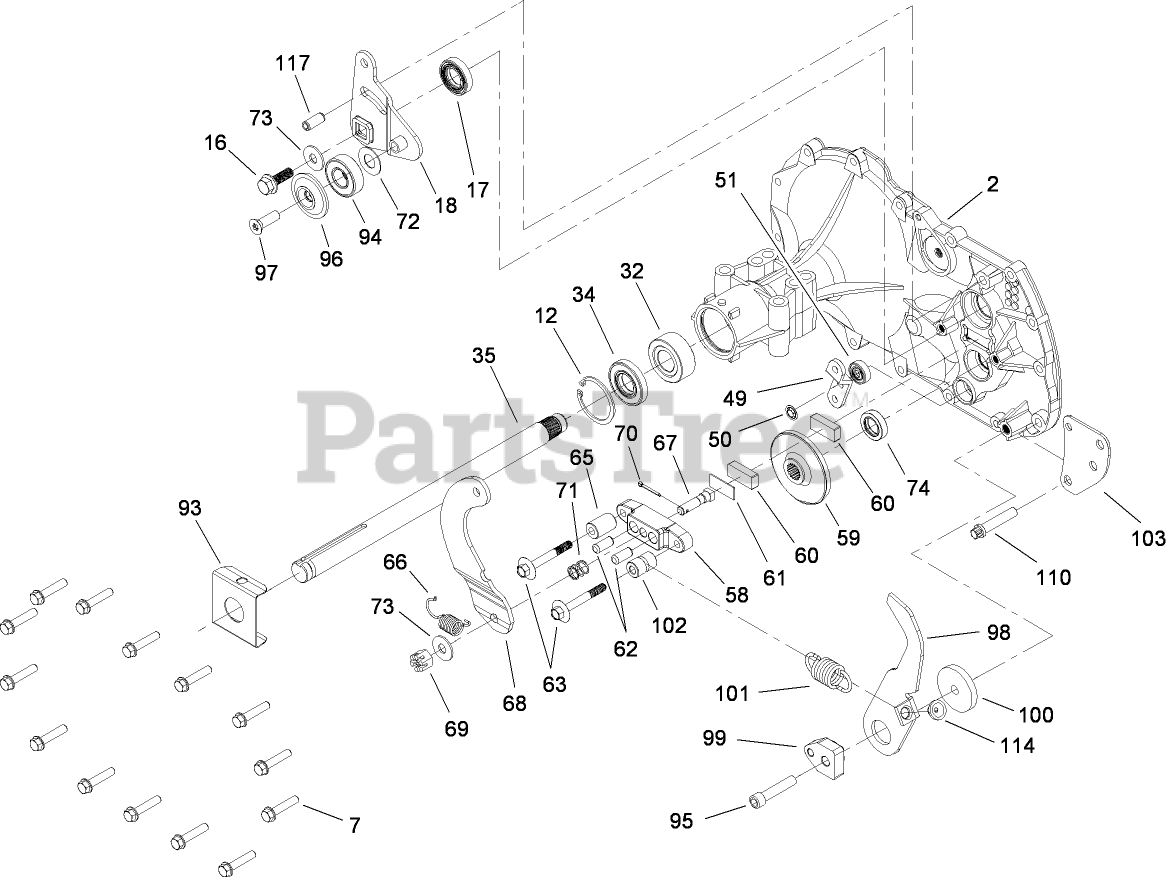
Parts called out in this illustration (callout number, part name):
2	SIDE HOUSING ASM
7	SCREW-HHF
12	RING-RETAINING
16	SCREW-HF
17	SEAL-LIP
18	ARM-CONTROL
32	BEARING-SLEEVE, OUTBOARD
34	SEAL-LIP
35	SHAFT-AXLE, RH
49	ARM-BYPASS
50	RING-RETAINING
51	SEAL-LIP
58	YOKE-BRAKE
59	ROTOR-BRAKE
60	PUCK-BRAKE
61	PUCK-PLATE
62	PIN-BRAKE
63	SCREW-HF
65	SPACER
66	SPRING-ARM, BRAKE (BIAS)
67	BOLT-SQH
68	ARM-BRAKE
69	NUT-CASTLE
70	PIN-COTTER
71	SPRING-BRAKE, ANTI DRAG
72	WASHER
73	WASHER-PIVOT
74	SEAL-OIL
93	CLIP-SPRING
94	BEARING
96	SPACER-LOCATING
97	SCREW-COUNTERSUNK
98	ARM-RETURN
99	PUCK-ADJUSTING
100	WASHER
101	SPRING-EXTENSION
102	SPACER
103	BRACKET-TORQUE
110	SCREW-TTH
114	GUIDE-SPRING
117	PIN-SPRING
